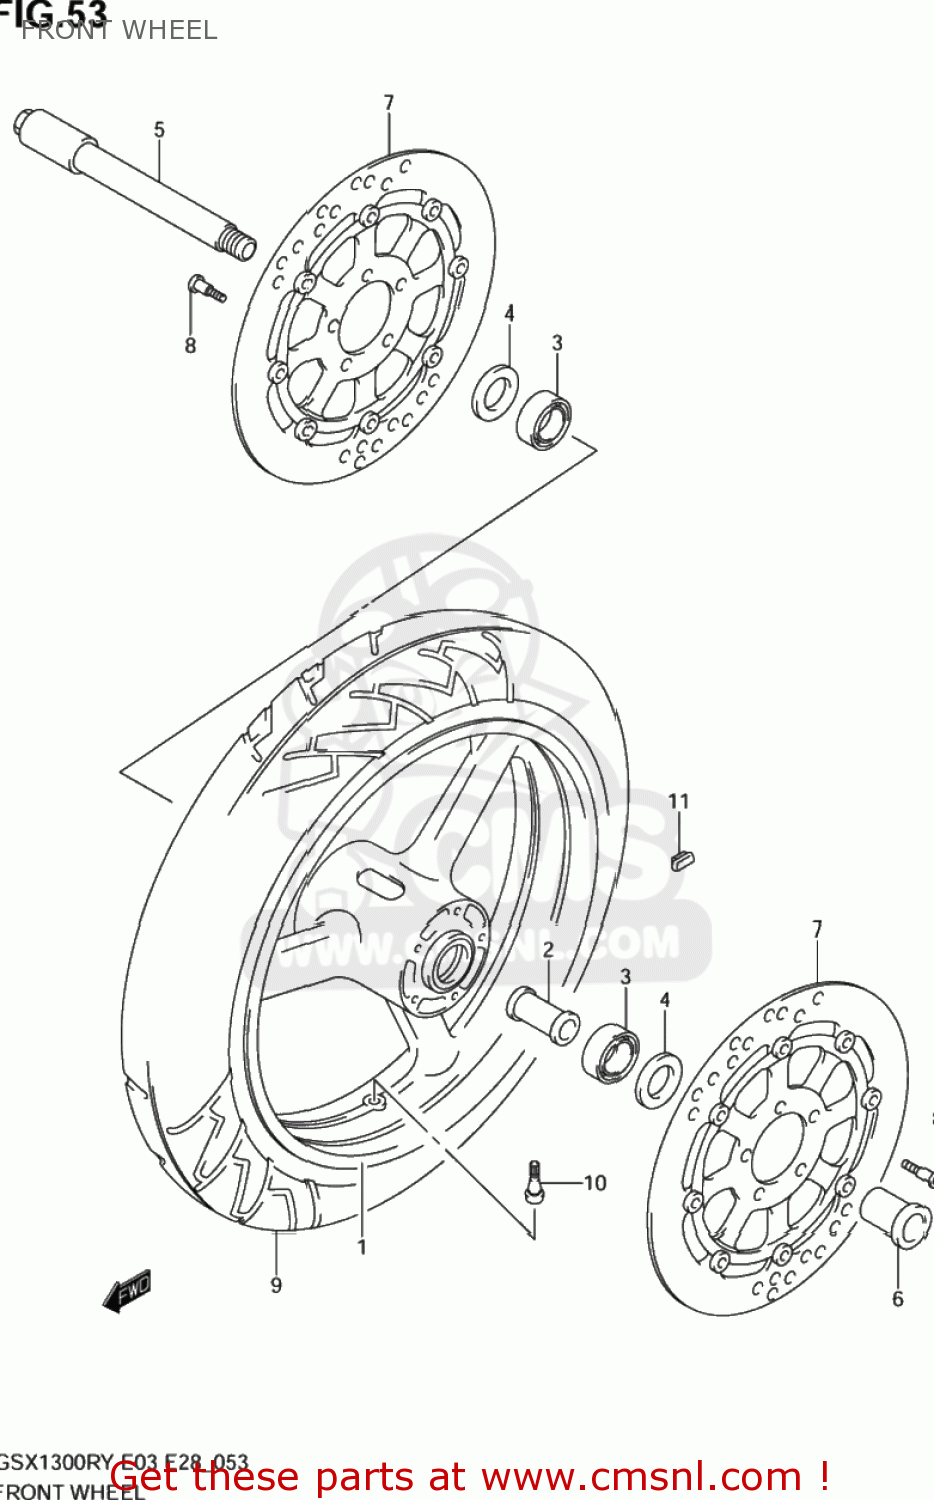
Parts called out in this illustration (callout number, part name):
1	WHEEL FRONT,17
2	SPACER,FR HUB BEARING
3	BEARING(25X52X15)
4	SEAL,OIL(32X52X7)
5	AXLE,FR
6	NUT,FR AXLE
7	DISC,FR BRAKE
8	BOLT 8X33
9	TIRE,FR(120/70 ZR17 58W)
10	VALVE ASSY,WHEEL RIM(TR412)
11	BALANCER,WHEEL (10G)
